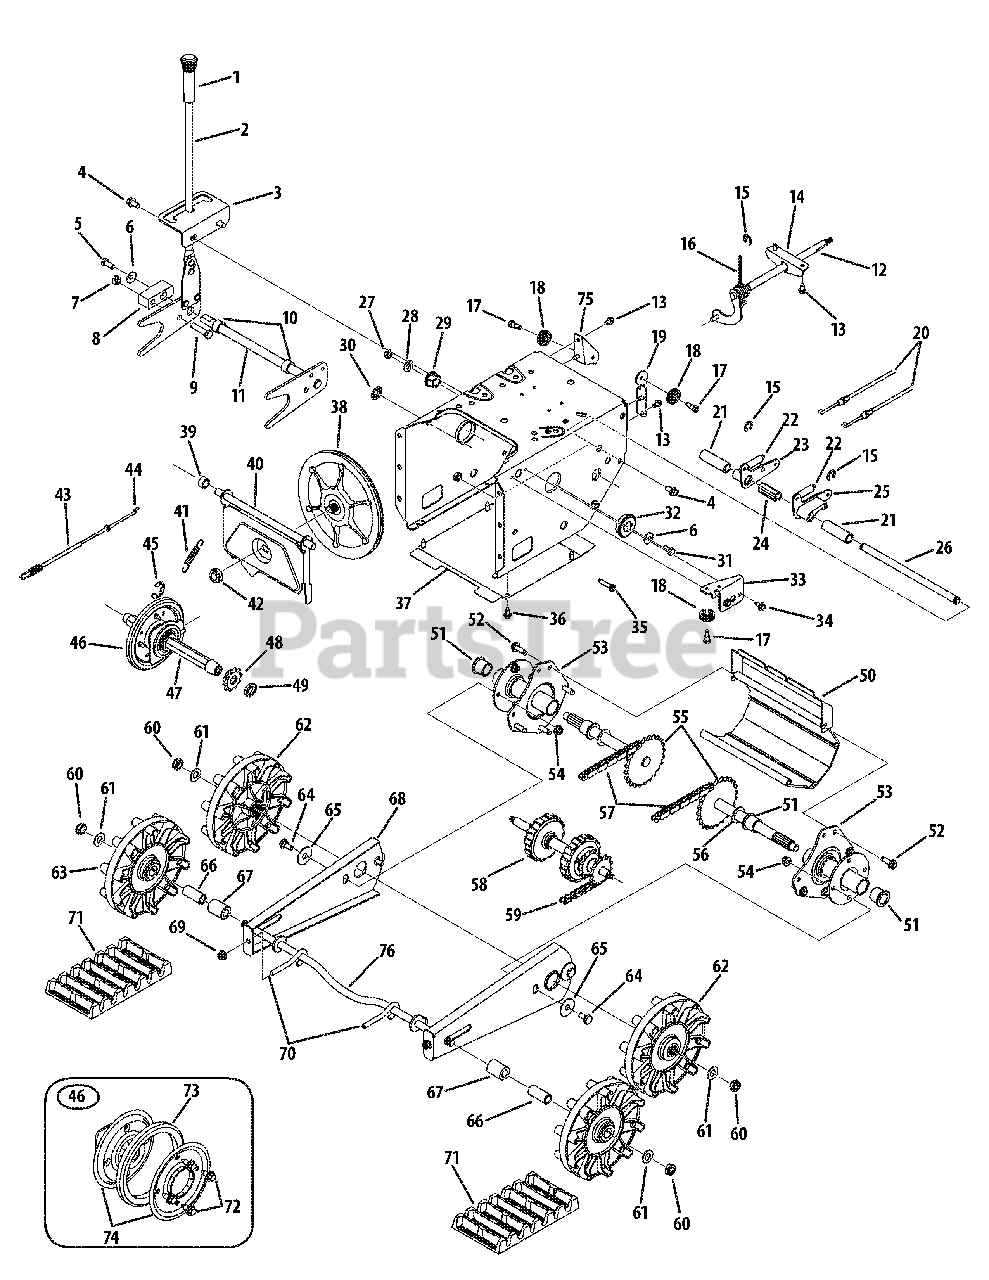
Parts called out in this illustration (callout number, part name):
1	Grip, .5 ID x 3.45
4	Hex Washer Screw, 5/16-18 x .750
5	Hex Screw, 5/16-24 x .75
6	Bell Washer, .340 x .872 x .060
7	Hex Lock Nut, 3/8 -16
8	Lift Shaft Drive
9	Hex Screw, 3/8 -16 x 1.50
10	Spacer, .828 ID x .875 OD x .500
12	Shift Rod Assembly
13	Hex Washer Screw, 1/4-20 x .500
15	E-Ring
16	Torsion Spring, .750 ID x .968
17	Shoulder Screw, .340 x .335 x 1/4-28
18	Cable Roller
21	Spacer, .515 x 735 x 2.44
22	Extension Spring, .48 OD x 2.03
23	Dogg Assembly, RH
24	Spacer, .491 ID x 1.87
25	Dogg Assembly, LH
26	Shift Actuator
27	Jam Lock Nut, 3/8-24
28	Flat Washer, .406 x .875 x .059
29	Hex Flange Bearing
30	Speed Nut, .500
31	Hex Lock Screw, 5/16-18 x .625
32	Ball Bearing
35	Hex Washer Screw, 1/4-20 x 1.000
36	Hex Washer Screw, 1/4-20 x .625
37	Track Frame Cover
38	Friction Wheel Disc Assembly
39	Spacer, .525 ID x .750 x .42
42	Flange Nut, 5/16-18
43	Drive Clutch Cable
44	Z-Fitting
46	Friction Wheel Assembly
47	Hex Track Shaft
48	Sprocket, 10T
49	Spacer, .675 ID x 1.00 OD x .23
50	Steering Cable Bracket
51	Flange Bearing
52	Hex Washer Screw,5/16-18 x 1.000
54	Flange Lock Nut, ,5/16-18
55	Track Axle Assembly
56	Flat Washer, .793 x 1.24 x .06
58	Drive Track Shift Assembly
60	Jam Lock Nut, 1/4-20
61	Flat Washer, .510 x 1.00 x .060
62	Track Drive Wheel
63	Track Idler Wheel
64	Shoulder Screw, .435 x .178-,5/16 x .58
65	Flat Washer, .442 x 1.38 x .060
66	Spacer, .51 ID x .75 OD x 1.67
67	Spacer, .510 ID x 1.00 OD x 1.34
70	Eye Bolt, ,5/16-18 x 3.0
71	Snow Trac
72	Hex Washer Screw, 1/4-14 x .625
73	Friction Wheel
74	Friction Plate
